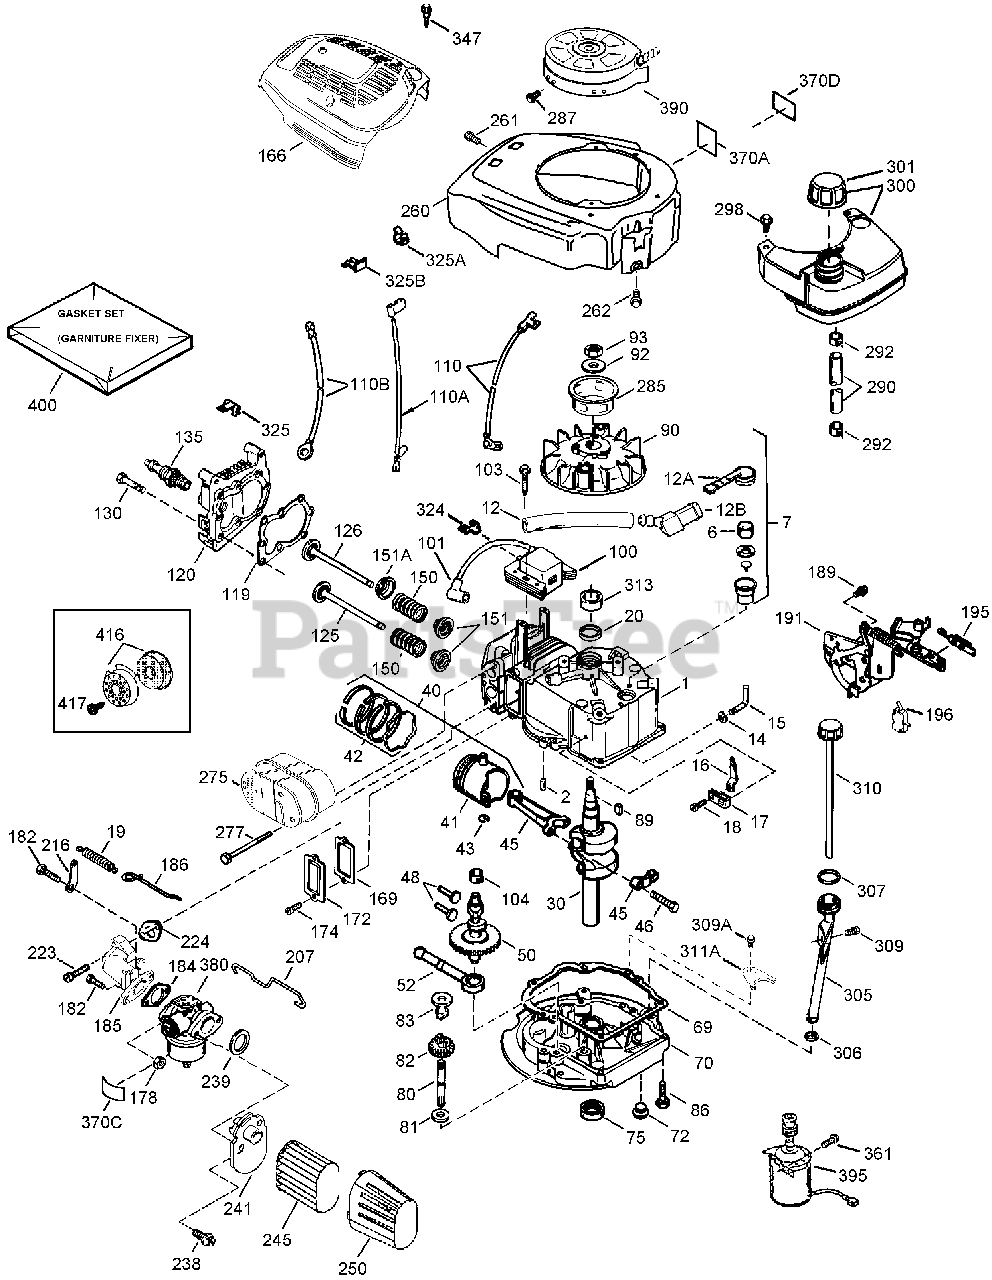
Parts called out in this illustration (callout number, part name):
324	Terminal
325	Clip-Wire
325A	Clip-Actuator, Brake Switch
325B	Wire Clip
347	Screw (10-32 x 27/32)
361	Screw (1/4-20 x 1/2)
370A	Decal-Lubrication
370C	Decal-Primer
370D	Decal-Warning
380	Carburetor ASM (Includes Gasket #26756)
390	Rewind Starter ASM
395	12-Volt Electric Starter Motor ASM
400	Gasket Set
416	Spark Arrestor Kit
417	Screw (8-32 x 3/8in)
